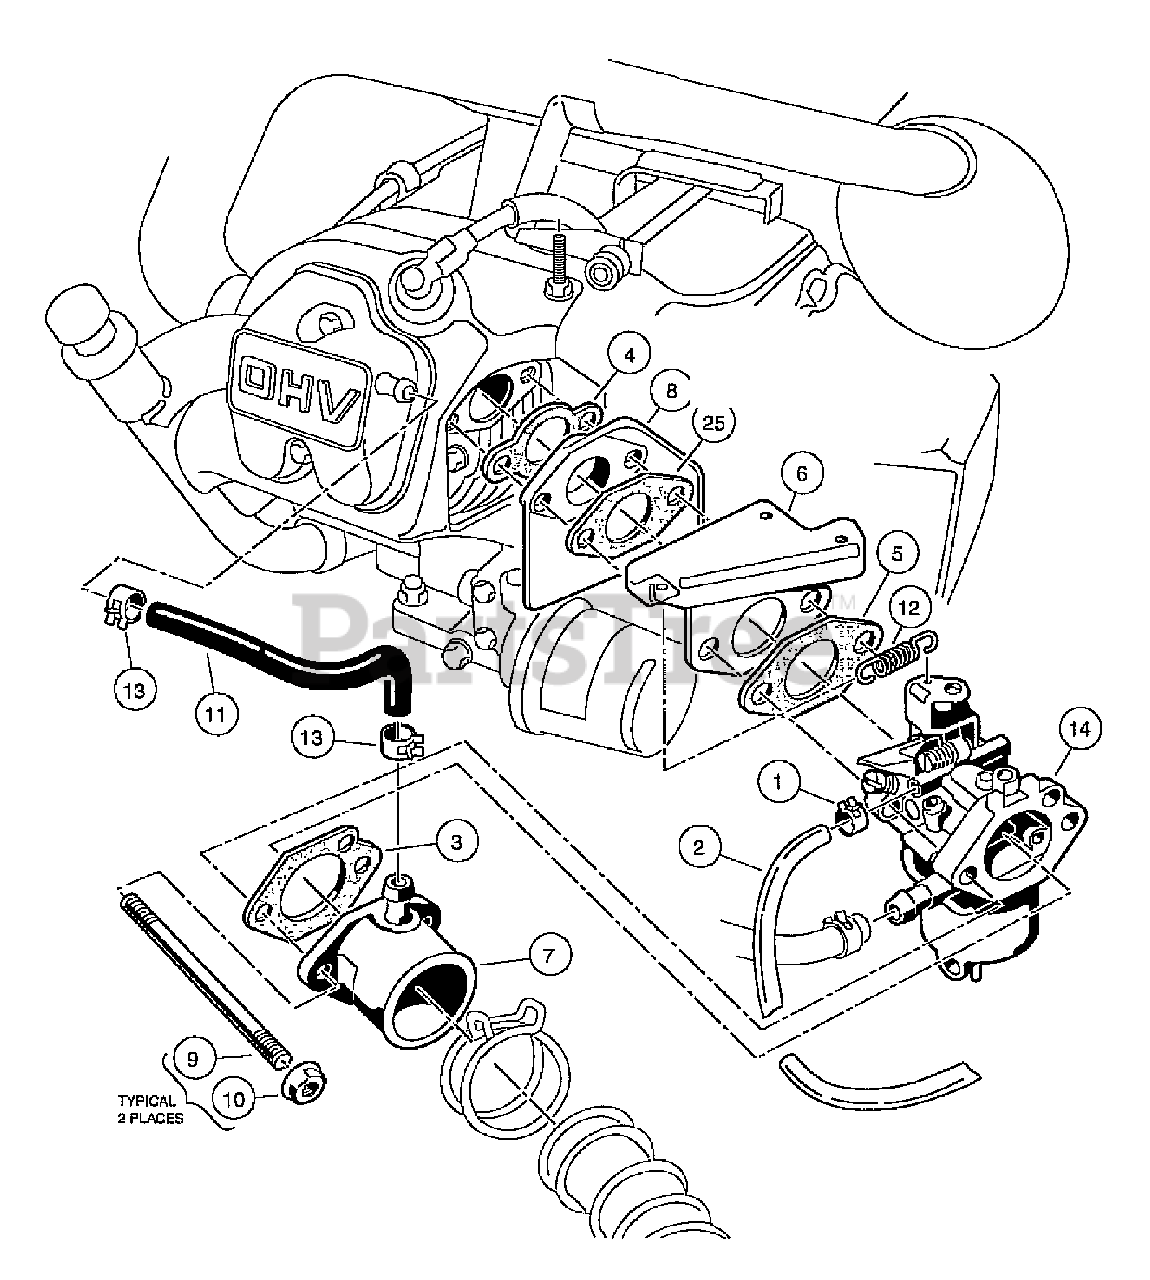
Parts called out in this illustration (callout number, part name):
1	Clamp, 0.301 ID Hose
2	Fuel Line
3	Gasket, Carb To Intake Manifold
4	Gasket, Engine To Insulator
5	Gasket, Sprg Brkt To Carb OHV
6	Bracket, Throttle Spring Return
7	Pipe, Intake Manifold
8	Insulator, Carburetor
9	Stud, M6-1.00 Two-Ended
11	Tube, Crankcase Vent
12	Spring, Throttle Return
14	Carburetor, FE350D
15	Jet, Altitude, # 85
16	Gasket, Carburetor Bowl OHV
17	Float Assembly
18	Screw Assembly
20	Chamber Assembly, Float
21	Screw Assembly
22	Jet, #40 Pilot
23	Nozzle, Main
24	Assembly, Pilot Air Screw
25	Gasket, Insulator To Bracket
